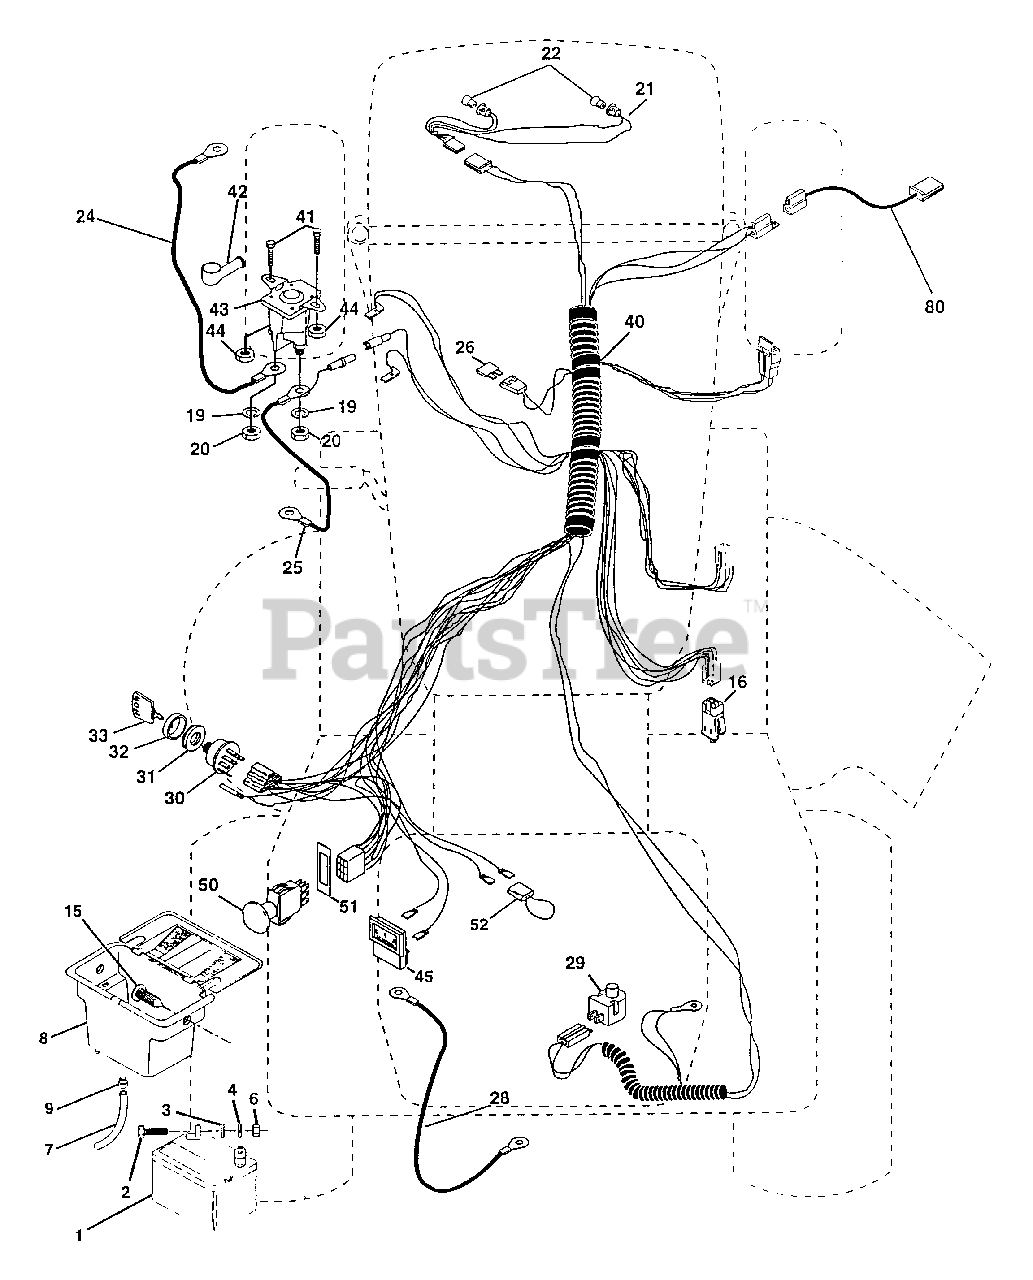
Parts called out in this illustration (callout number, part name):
1	Battery 12 Volt 30 AMP (AYP part number)
2	Bolt Hex Hd 1/4-20 UNC X 3/4
3	Washer 9/32 X 5/8 X 16 Ga.
4	Washer Lock Hvy Helical 1/4
6	Nut Fin Hex 1/4-20 UNC
7	Tube Plastic 12"
8	Case Battery Mech Hinge
9	Clamp Hose Olive
15	Fastener Snap-In
16	Switch Interlock Push-In (AYP part number)
19	Washer Lock 1/4 (AYP part number)
20	Nut Jam Hex 1/4-20 UNC
21	Harness Asm Light W/4152j
22	Bulb Light #1156
24	Cable Battery 6 Ga 16" red
25	Cable Battery 6 Ga 44" red w/16 wire
26	Fuse 30 AMP Auto Green
28	Cable Ground 6 Ga 12" black
29	Switch Plunger Nc Gray
30	Switch Ign 4 pos w/lights
31	Nut Ignition
32	Cover Sw Ignition
33	Key Ign Molded Indak
40	Harness Ign.
41	Bolt Blk Fin Hex 1/4 - 20 x 1/2
42	Cover Terminal Red
43	Solenoid (AYP part number)
44	Nut Keps Hex 1/4-20 UNC
45	Ammeter Rectangular 6amp (AYP part number)
50	Switch, PTO 3PDT Black Delta 96
51	Ring Retainer PTO
52	Protection Wire Loop
80	Harness, Clutch EVX
